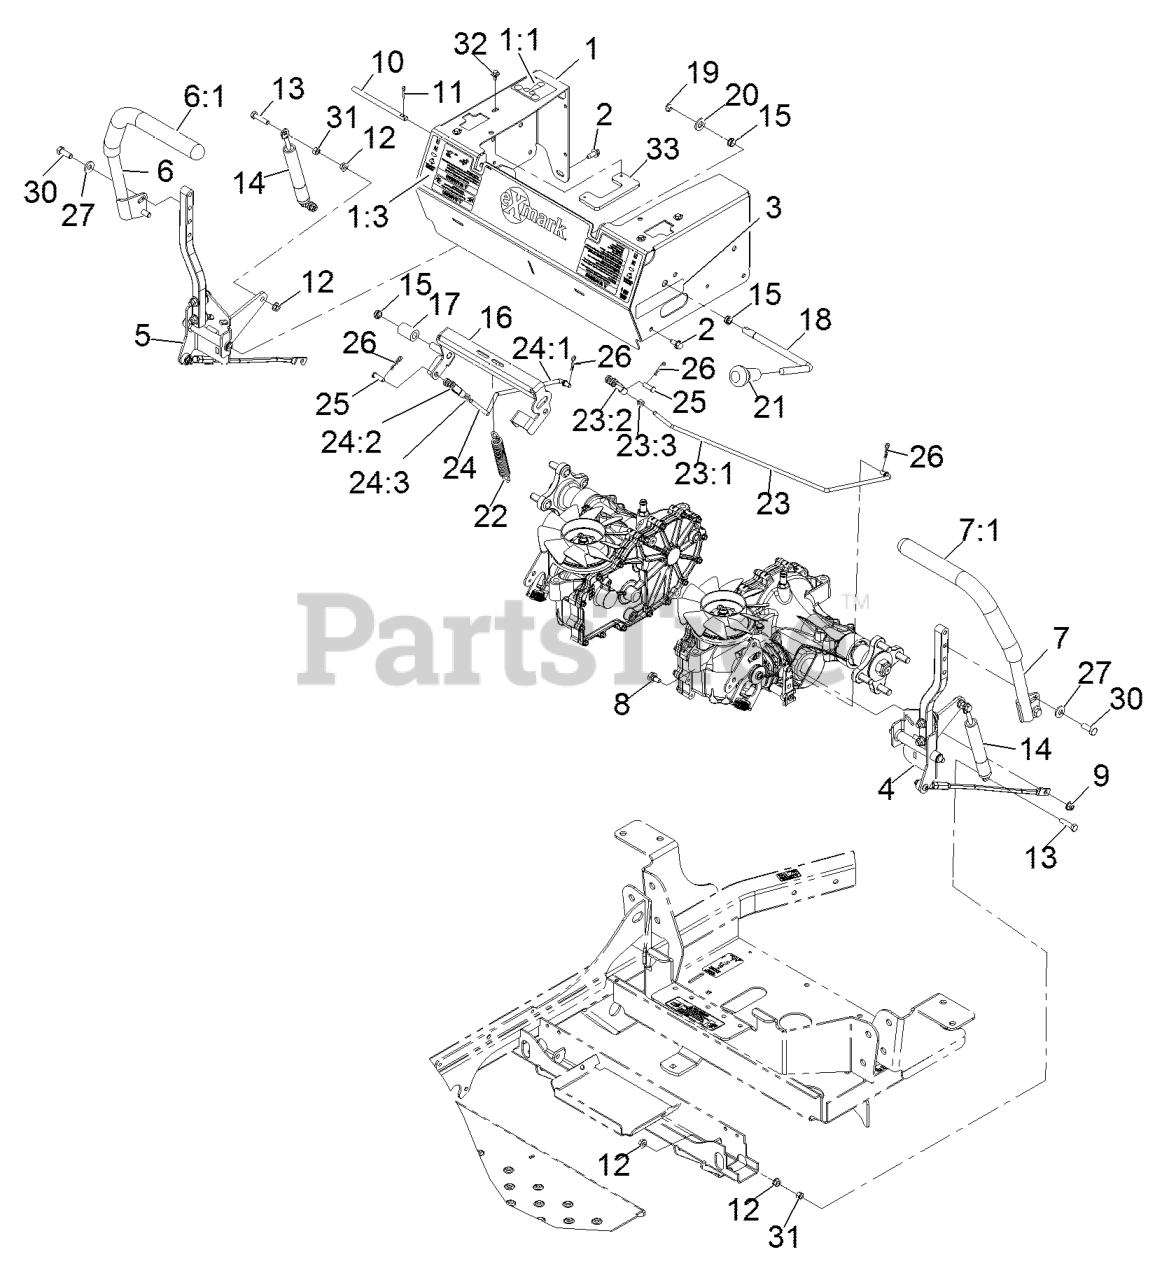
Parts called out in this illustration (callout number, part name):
1	ASM-MOT CTRL FRM W/DCL
1:1	DECAL-ROUTING, BELT
2	Screw-HWH 5/16-18 X 3/4 Tf
3	DECAL-S-SERIES
4	Motion Control Asm-Lh
5	Motion Control Asm-Rh
6	RH HANDLE ASM
7	LH HANDLE ASM
8	BOLT-SHOULDER,HFH
9	NUT-HF, NI
10	PIN-CONTROL PIVOT
11	PIN-COTTER
13	SCREW-HH
14	DAMPER-MOTION CONTROL
15	BUSHING,SNAP
16	ASM-BRAKE CENTER ARM
18	HANDLE,BRAKE
19	RING-RETAINING, EXTERNAL
20	WASHER-FLAT
22	SPRING-DECK, ENGAGEMENT
23	BRAKE LINKAGE ASM-LH
23:1	LINKAGE,BRAKE LH
23:2	YOKE-ADJUSTABLE
23:3	NUT-JAM
24	BRAKE LINKAGE ASM-RH
24:1	LINKAGE-BRAKE, RH
24:2	YOKE-ADJUSTABLE
24:3	NUT-JAM
25	PIN-CLEVIS
26	PIN-COTTER
27	WASHER-BELLEVILLE
30	SCREW-HH
31	NUT-HEX
32	SCREW-HHFTF
33	STOP-MOTION CONTROL
